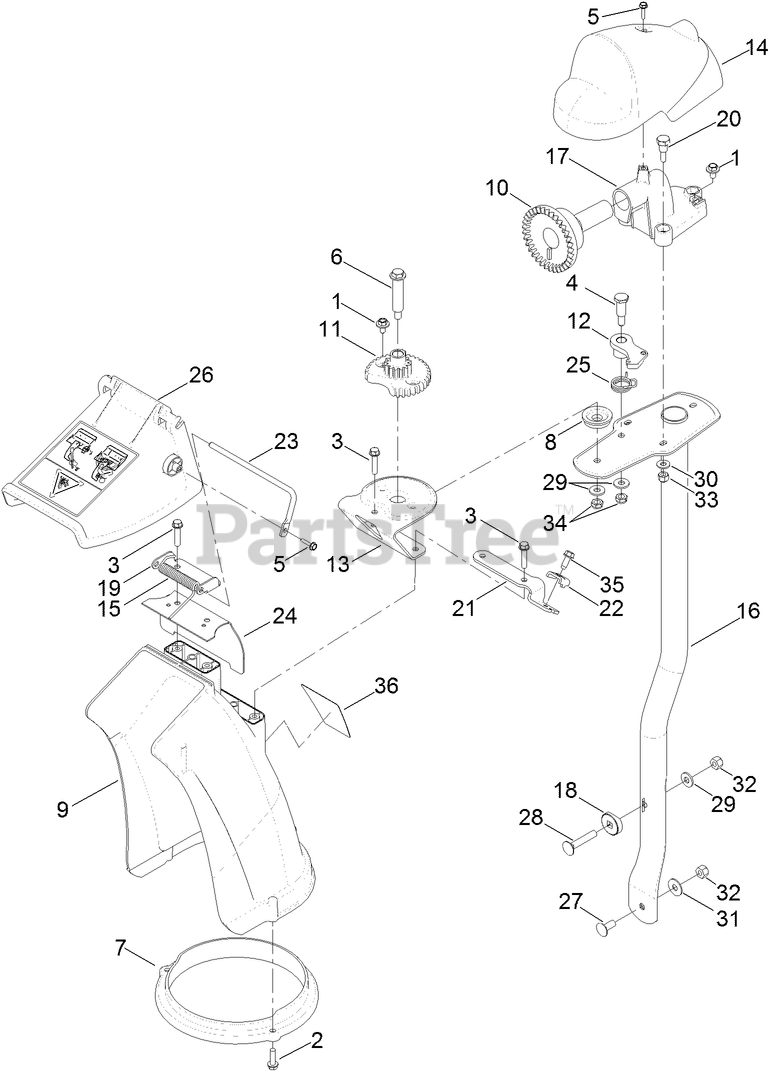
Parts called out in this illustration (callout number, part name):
1	SCREW AND WASHER ASM
2	SCREW-HWH
3	SCREW-PLASTITE
4	SCREW-SHOULDER
5	SCREW-HWH
6	BOLT-SHOULDER
7	RING-CHUTE
8	SPACER-CHUTE
9	CHUTE-DISCHARGE
10	GEAR-FACE
11	GEAR-CHUTE
12	LATCH-CHUTE
13	BRACKET-SUPPORT, CHUTE
14	COVER-GEAR, CHUTE
15	SPRING-TORSION
16	TUBE-SUPPORT
17	MOUNT-GEAR, FACE
18	WASHER-CURVED
19	BRACKET-DEFLECTOR
20	SCREW-SHOULDER
21	BRACKET-CABLE, CLAMP
22	CLAMP-CABLE
23	ROD-DEFLECTOR
24	SEAL-CHUTE
25	SPRING-TORSION
26	DEFLECTOR-CHUTE, CE
27	SCREW-CARR
28	BOLT-CAR
29	WASHER-FLAT
30	WASHER-FLAT
31	WASHER-BELLEVILLE
32	NUT-LOCK, NI
33	NUT-LOCK, NI
34	NUT-LOCK, NI
35	SCREW-HWH
36	DECAL-GUARANTEE
